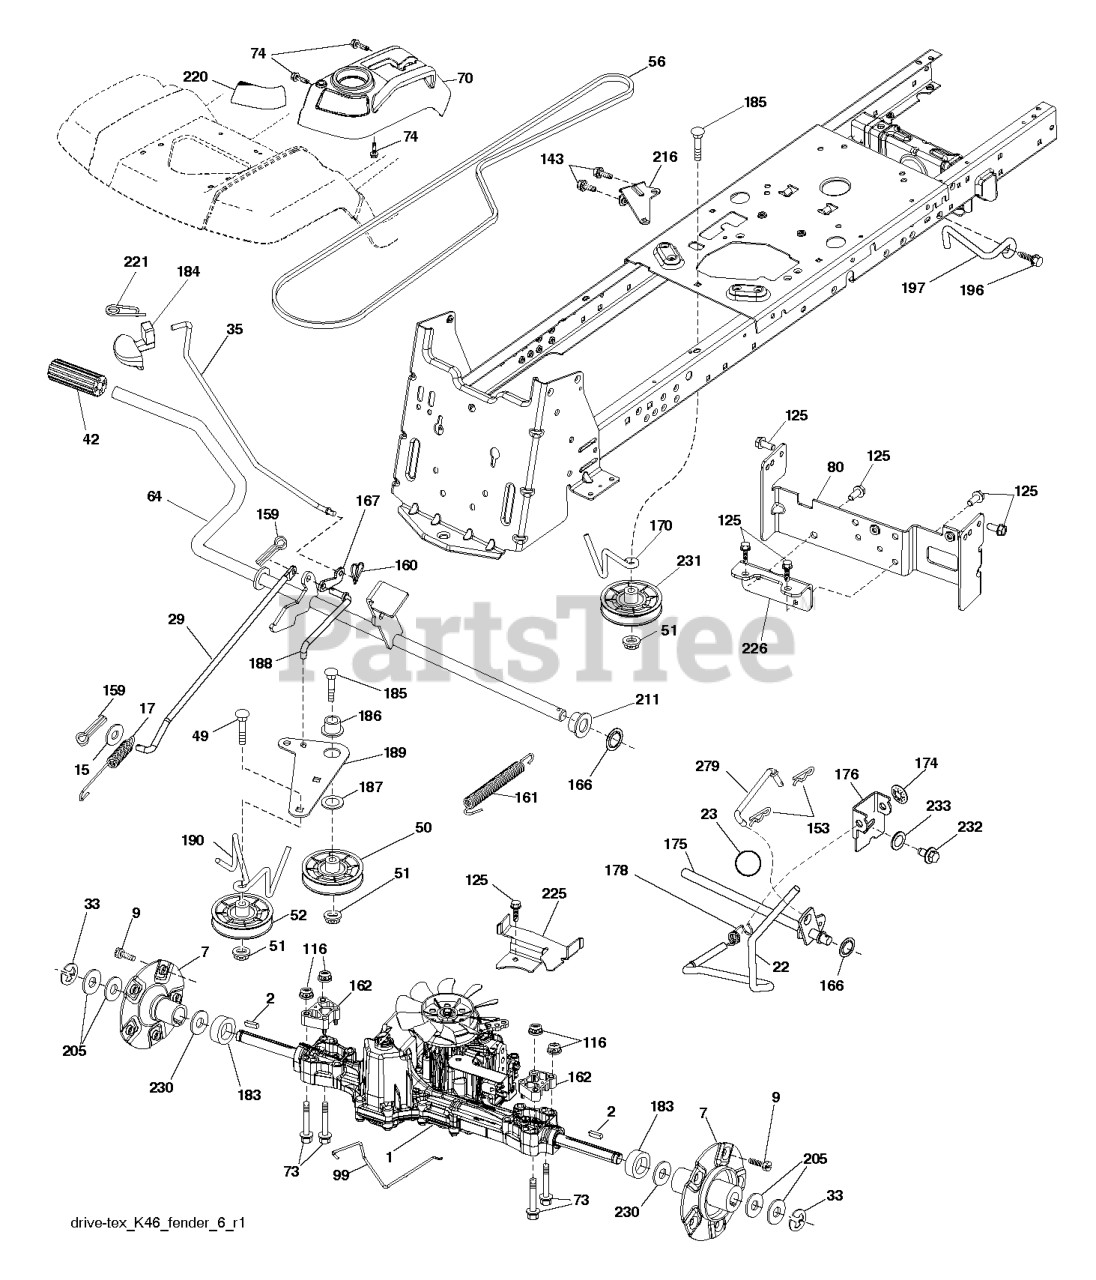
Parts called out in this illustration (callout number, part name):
2	KEY.SQUARE.187X2.500
7	HUB.ASM.WHEEL.REAR.22"
9	HUB BOLT
15	WASHER
17	SPRING.BRAKE.K46.GREEN
22	ROD.SHIFT.FENDER.STGT.
23	KNOB.DELUXE.(PISTOL.GRIP).BLAC
29	ROD.BRAKE.K46
35	ROD.BRAKE.PARKING.GT.H
42	PEDAL COVER T
49	BOLT
50	IDLER.FLAT.910.OFFSET
51	NUT LOCK FLG 3/8-16 UNC
52	IDLER.V-GROOVE.910.OFFSET
56	V-BELT.MOWER.92.40.42/K46
64	SHAFT.ASM.PEDAL.BRAKE.
70	RP CONSOLE.ASM.HYDO.HUSQ.
73	BOLT.HEX.FLNG.5/16-18X3.75
74	SCREW.HI-LO.CONSOLE
80	STRAP TORQUE
99	ROD.SPRING.BYPASS.K46.TEX.GT
116	NUT LOCK HEX FLANGE 5/16-18
125	SCREW
143	SCREW LT
153	RETAINER M
159	COTTER PIN
160	RETAINER CLIP
161	SPRING, RETURN LT
162	SPACER.TRANSAXLE.18&22
166	NUT.PUSH.625
167	LATCH.BRAKE.SPRING
170	KEEPER.CENTER SPAN.1.688
174	NUT.PUSH.500.2006
175	SHAFT ASM SHIFT
176	ARM.CLEVIS.ROD.SHIFT
178	SPRING.SHIFT.GT2006
183	SPACER.SPLIT.800X.350
184	HANDLE.PARKG.BRK.HUSQ X667
186	SPACER.RETAINER
187	WASHER 12/32X2X10GA
188	RP.LINK.CLUTCH.GROUND.DRIVE
189	BELLCRANK.GROUND.DRIVE.TEX.
190	KEEPER.BELLCRANK.DRIVE
196	SCREW 3/8-16X1
197	BRKT.ANIT-ROTATION.CLUTCH
211	BUSHING.SHAFT.BRAKE.HAND
216	BRACKET.PULLEY.IDLER.W/TEX
220	REFLECTOR.RH.TEX GT
221	RETAINER.SPRING.CLIP.H
225	KEEPER.BELT.TRANSAXLE.K46
226	BRKT.MOUNT.TORQUE.K46.
230	WASHER.HARDENED
231	IDLER.V-GROOVE.1.688.OFFSET
232	BOLT FIN HEX 7/16-14 X 1
233	WASHER SERRATED
279	LINK.SHIFT.T/A.K46.FEND.TX
